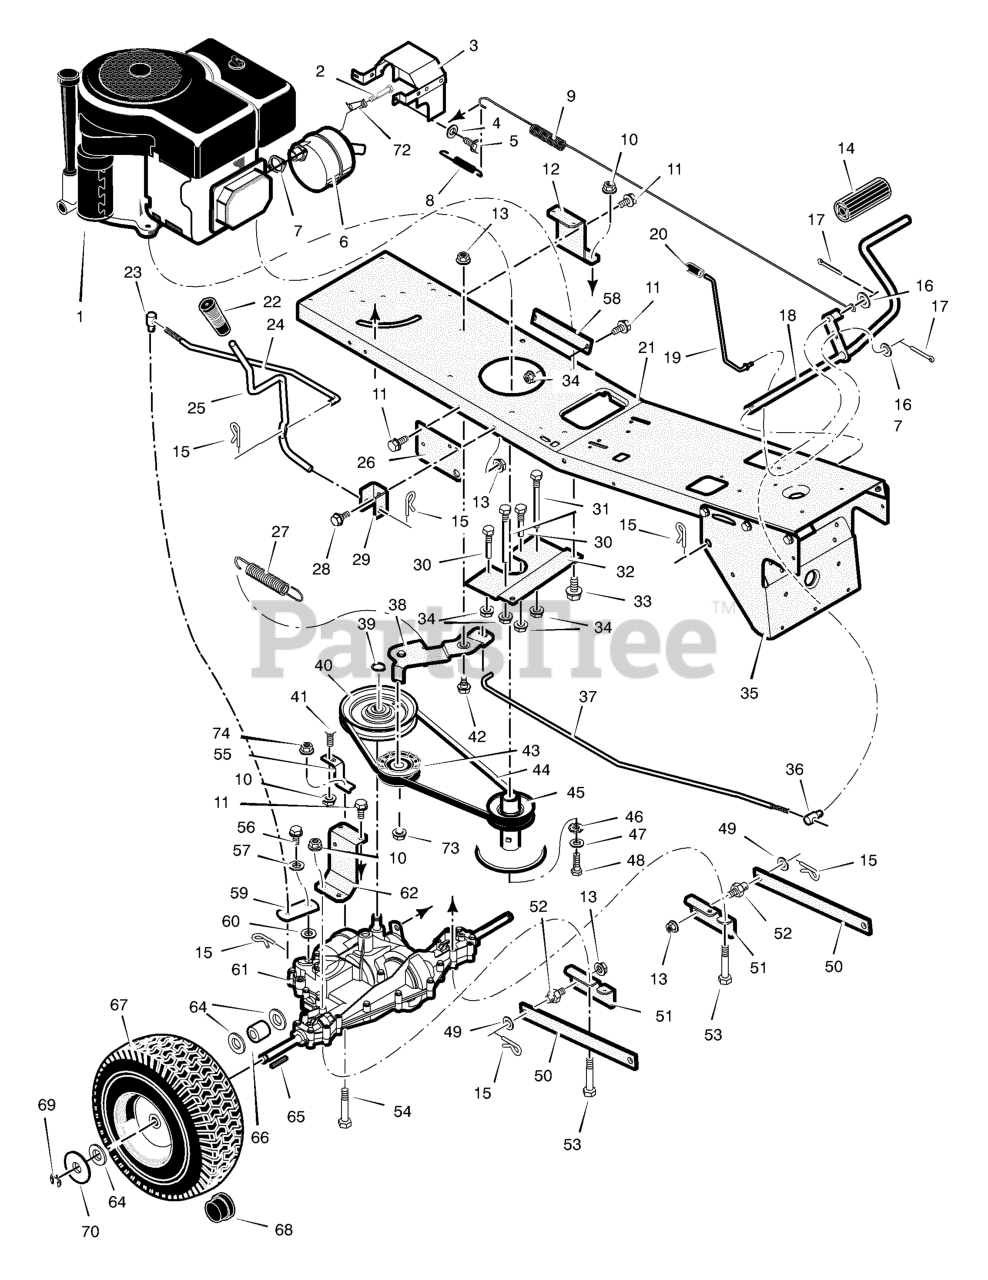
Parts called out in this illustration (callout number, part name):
1	Engine, Briggs & Stratton *
2	Bolt, Hex
3	Shield Assembly, Heat
4	Lockwasher
5	Screw
6	Muffler
7	GASKET, Exhaust
8	Spring, Extension
9	Spring, Extension
10	Nut
12	Bracket, Transaxle -LH
13	Nut, Flange
14	Cover, Pedal
15	Pin, Cotter
16	Washer
17	Pin, Cotter
18	Pedal Assembly
19	Rod, Parking Brake
20	Grip, Parking Brake Rod
22	Grip, Shift Lever
23	Nut, Adjusting
24	Link, Shift
25	Lever, Shift
26	Bracket, Lift Pivot
27	Spring, Extension
28	Bolt, Shoulder
29	Bracket, Pivot
30	Guide, Belt -Short
31	Guide, Belt -Long
32	Plate, Belt Guide
33	Bolt
34	Nut, Flange
35	Bracket, Support
36	Nut, Adjusting
37	Rod, Clutch
38	Clutch Arm Assembly
39	Ring, Retainer
40	Pulley, Drive
41	Bolt, Carriage
42	Bolt, Shoulder
43	Pulley, Idler
44	Belt, Motion Drive
45	Pulley, Split Stack
46	Washer, Star
48	Bolt, Hex
49	Washer
51	Bracket, Rear Hanger
52	Pin, Threaded Shoulder
53	Bolt, Hex
55	Bracket, Torque Reactor
57	Washer, Shift Yoke
58	Plate, Reinforcement
59	Yoke, Shift
61	Transaxle, Peerless **
62	Bracket, Transaxle -RH
65	Key, Square
66	SPACER, Rear Wheel
67	Wheel, Rear -15"
68	Cap, Hub
72	Lock, Screw
73	Nut
74	Nut
